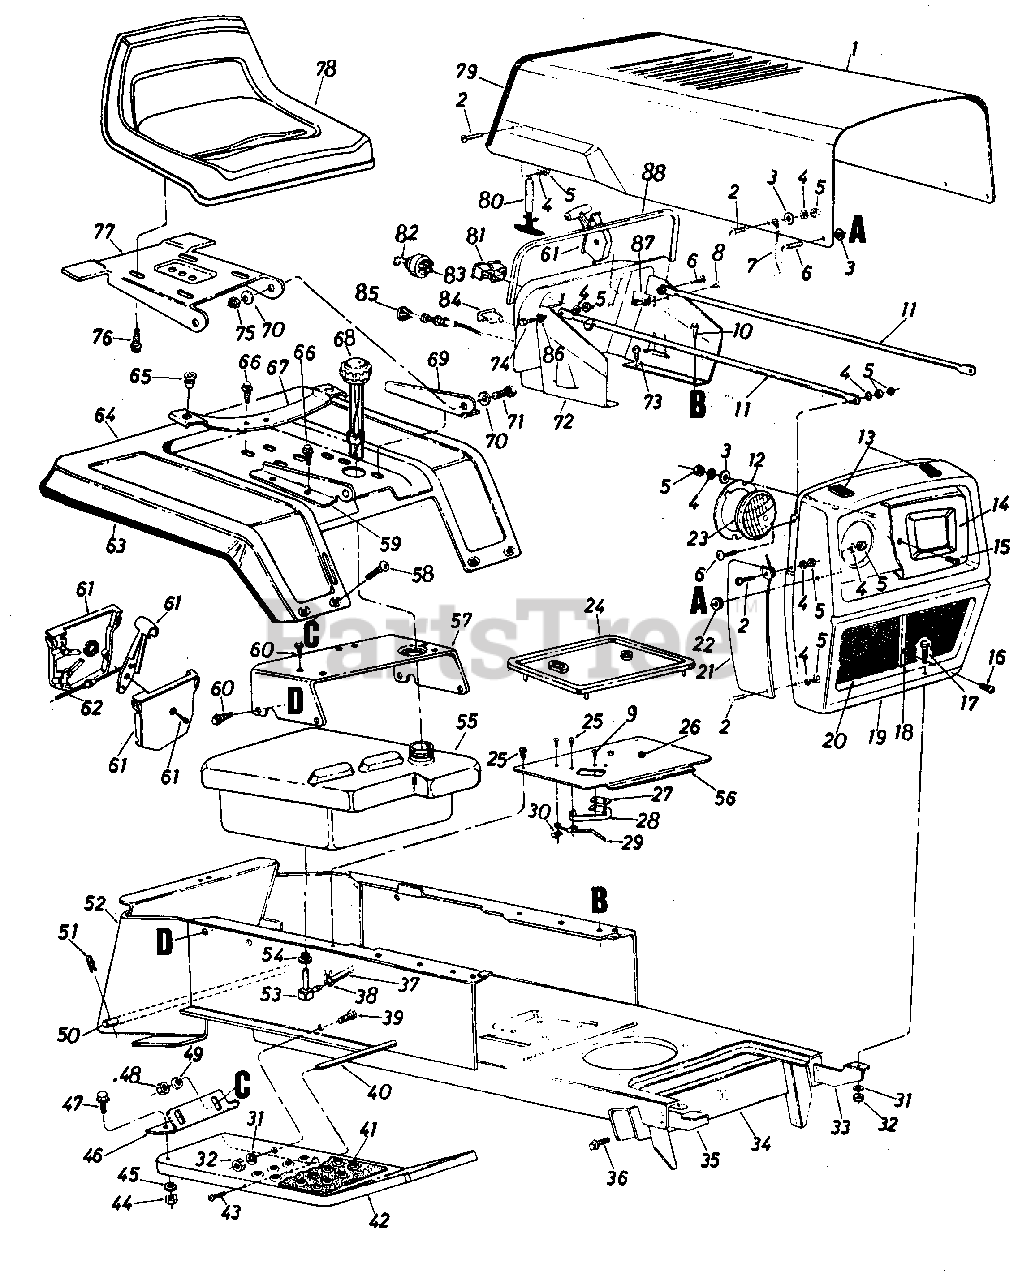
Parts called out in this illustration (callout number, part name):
3	Fl-Wash. 1/4" I.D.
4	L-Wash. 1/4" I.D.*
5	Hex Nut 1/4-20 Thd.*
6	Truss Mach. Scr. 1/4-20 x .75" Lg.*
7	Hood Stop
8	Hex Tap Scr. #10 x .50" Lg.*
9	Hex Wash. Hd. AB-Tap Scr. #8 x .38" Lg.
10	Hex Thd. Rolling Scr. 1/4" x .50" Lg.
11	Grille Positioning Rod
12	Head Lamp Retainer
13	PVC Foam Strip 1/2" x 1.00 " x 2.00 " Lg. .
14	Head Lamp Bezel
15	Truss Mach. Scr. #10-24 x .38" Lg.
16	Truss Mach. Scr. #10-24 x .62" Lg.
17	Hex Bolt 5/16-18 x .75" Lg.*
18	Center Moulding
19	Grille Chrome
20	Grille Insert Screen
21	Grille Side Panel R.H.
21	Grille Side Panel L.H.
22	Rubber Wash. .50" I.D. x 1.0" O.D. .25 Thk.
23	Head Lamp
24	Trans. Cover-Bezel
25	Truss Hd. Scr. #10 x .50" Lg.
26	Snap Bushing
27	Insulator Nut Plate
28	Switch Spring
29	Shift Lever Spring
30	Speed Nut #10-24 U-Type
31	L-Wash. 5/16" I.D.*
32	Hex Nut 5/16-18 Thd.*
33	Grille Mount Brkt. L.H.
34	Lower Frame Ass'y.
35	Grille Mount Brkt. R.H.
36	Hex Thd. Rolling Scr. 5/16" x.75" Lg.
37	Gas Line 46" Lg.
38	Hose Clamp 3/8 "
39	Hex Bolt 5/16-18 x .75" Lg.*
40	Running Board Rod
41	Foot Pad
42	Running Board R.H.
42	Running Board L.H.
43	Truss Mach. Scr. 5/16-18 x .75" Lq.
44	Hex Nut 5/16-18 Thd.*
45	Bell-Wash. .34" I.D. x .87 O.D.
46	Fender Brkt. R.H.
48	Hex Nut 1/4-20 Thd.*
49	L-Wash. 1/4" I.D.*
50	Hitch Rod
51	Internal Cotter Pin
52	Hitch Plate
53	90ø Nipple
54	Bushing
55	Fuel Tank
56	Trans. Cover
57	Seat Mounting Channel
58	Carriage Bolt 1/4-20 x .50" Lg.*
59	Seat Bracket R.H.
60	Hex Thd. Rolling Scr. 5/16-24 x .75" Lg.
61	Throttle Control Box Ass'y.
62	Throttle Control Wire
63	Trim Strip 81"
66	Hex Wash. Hd. Self-Tap Scr. 5/16-18 x .50" Lg.
67	Seat Spring
68	Gas Cap w/ Gauge
69	Seat Bracket L.H.
70	Bell-Wash. .34" I.D. x .88" O.D.
71	Hex Bolt 5/16-18 x .75" Lg.*
72	Dash Panel Ass'y.
73	Hex Thd. Rolling Scr. 5/16-24 x .75" Lg.
74	Truss Mach. Scr. 1/4-20 x .75" Lg.*
75	Hex Cent. L-Nut 5/16-18 Thd.
76	Hex Wash. Hd. AB-Tap Scr. 3/8 x .75" Lg.
78	Seat Ass'y.
79	Vinyl Moulding Strip 30"
80	Hood Latch Ass'y.
81	Ammeter
82	Ignition Key
83	Ignition Switch
84	Light Switch
85	Choke Control Comp.
86	External Wash. 1/4" I.D.
87	Circuit Breaker 8 Amp.
88	Vinyl Moulding Strip 29"
